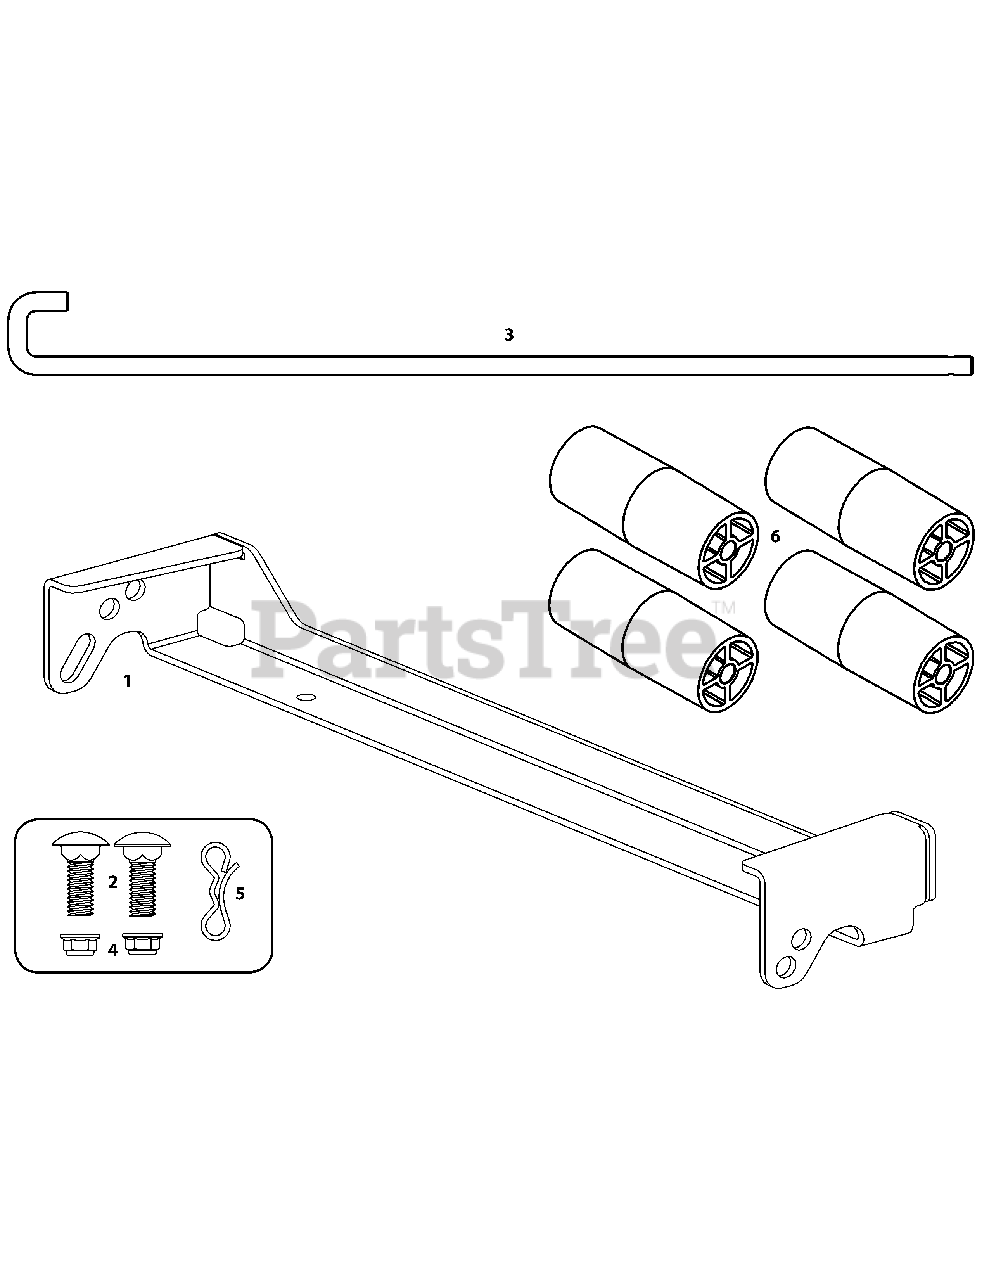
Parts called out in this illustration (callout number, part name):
1	Roller Bracket
2	Carriage Bolt, 3/8-16 x 1.00
3	Roller J-hook, 26"
4	Flange Lock Nut, 3/8-16
5	Bow-tie Cotter Pin, 91
6	Front Roller
